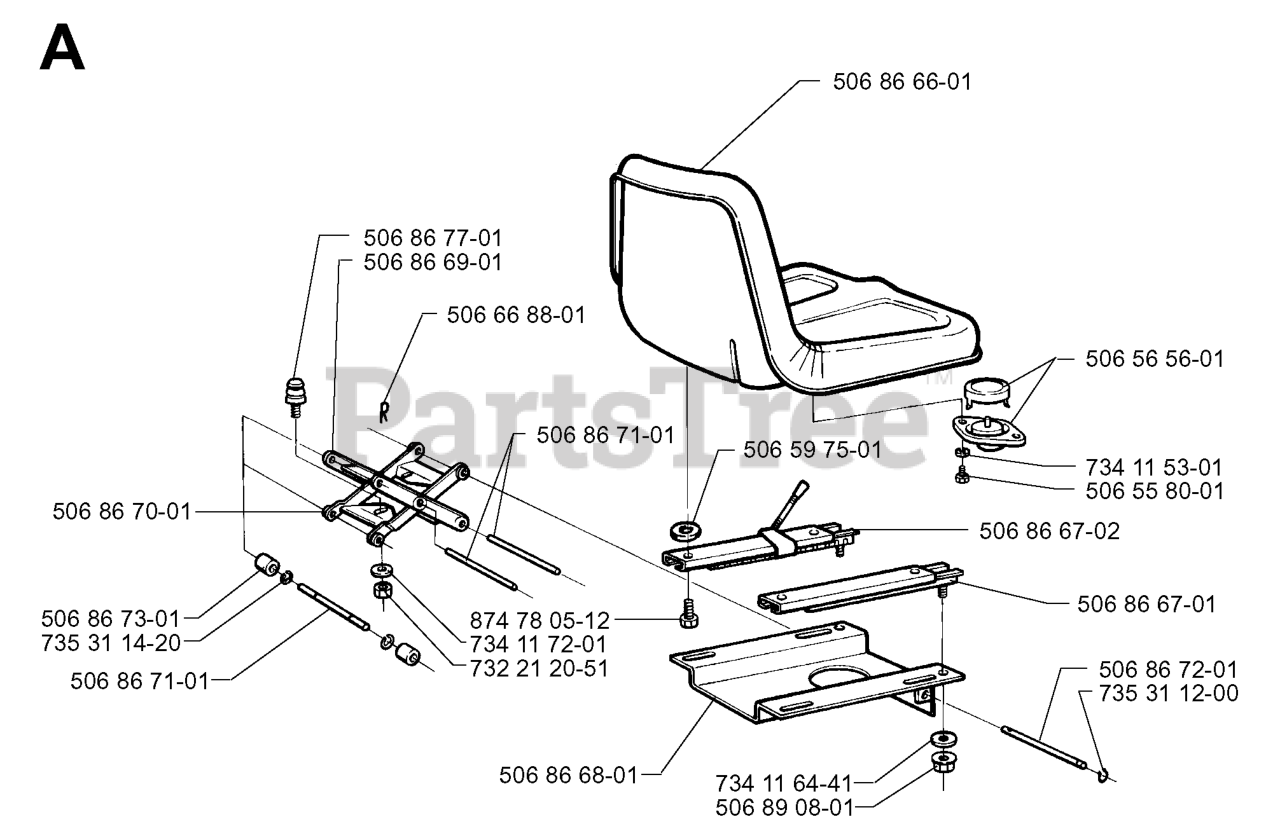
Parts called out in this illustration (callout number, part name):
1	DECK.WLDMT.W/TUBES.48"MS422
6	COVER.MANDREL.LH.48"(2 2)
7	COVER.MANDREL.RH.48"
8	BOLT.WASHER.ASM.7/16-2
11	48" HI-LIFT BLADE
12	ROD.ANTI.SWAY.48/54"K4
13	SHAFT ASM MANDREL
14	RP.HOUSING.MANDREL.4PT.
16	WASHER
17	BOLT.CARR.5/16-18X5/8.SHORT
18	BOLT
19	PIN.COTTER.5/16.BOW TI
20	BAFFLE, VORTEX MWR
21	LOCKNUT
22	STRIPPER.MANDREL.ROUND.BLACK
24	CAP-SLEEVE LT
25	SPRING, TORSION
26	NUT PUSH M
27	DEFLECTOR SUBS TO 532 180655
29	ROD.HINGE
30	SCREW, WASHER HEAD
31	WASHER.SPACER.MANDREL
32	PULLEY MANDREL
33	NUT.FLANGE.LOCK.TOP
39	RB PULLEY.IDLER.4.50/HUB SPEC
46	SCREW.1/4-20X5/8
47	BELT.DRIVE.DECK
48	PULLEY.IDLER.48"PRIMARY
49	NUT LOCK FLG 3/8-16 UNC
50	SCREW TT 3/8-16X2-1/4 UNC
52	PULLEY.IDLER.2006
54	BOLT.3/8-16X1.50
98	SPRING, DECK DRIVE
114	ROD.TENSION.RELIEF.TEX (2 2)
116	BOLT.SHOULDER.3/8-16X3-5/8.
117	RP WHEEL. GUAGE RALLY
120	WASHER
122	BUSHING.RELIEF.TENSION
185	NUT.LOCK.FLANGE.7/16
187	STUD.FASTNER.W/ANTI-ROTATE
188	NUT LOCK HEX FLANGE 5/16-18
189	ARM.SUSPENSION.MOWER
190	BOLT.SHOULDER
194	BOLT.CARR.SQNK.7/16
241	SCREW.TT.#10-32X.5.3/8.FLANGE
242	PORT.WASHOUT
